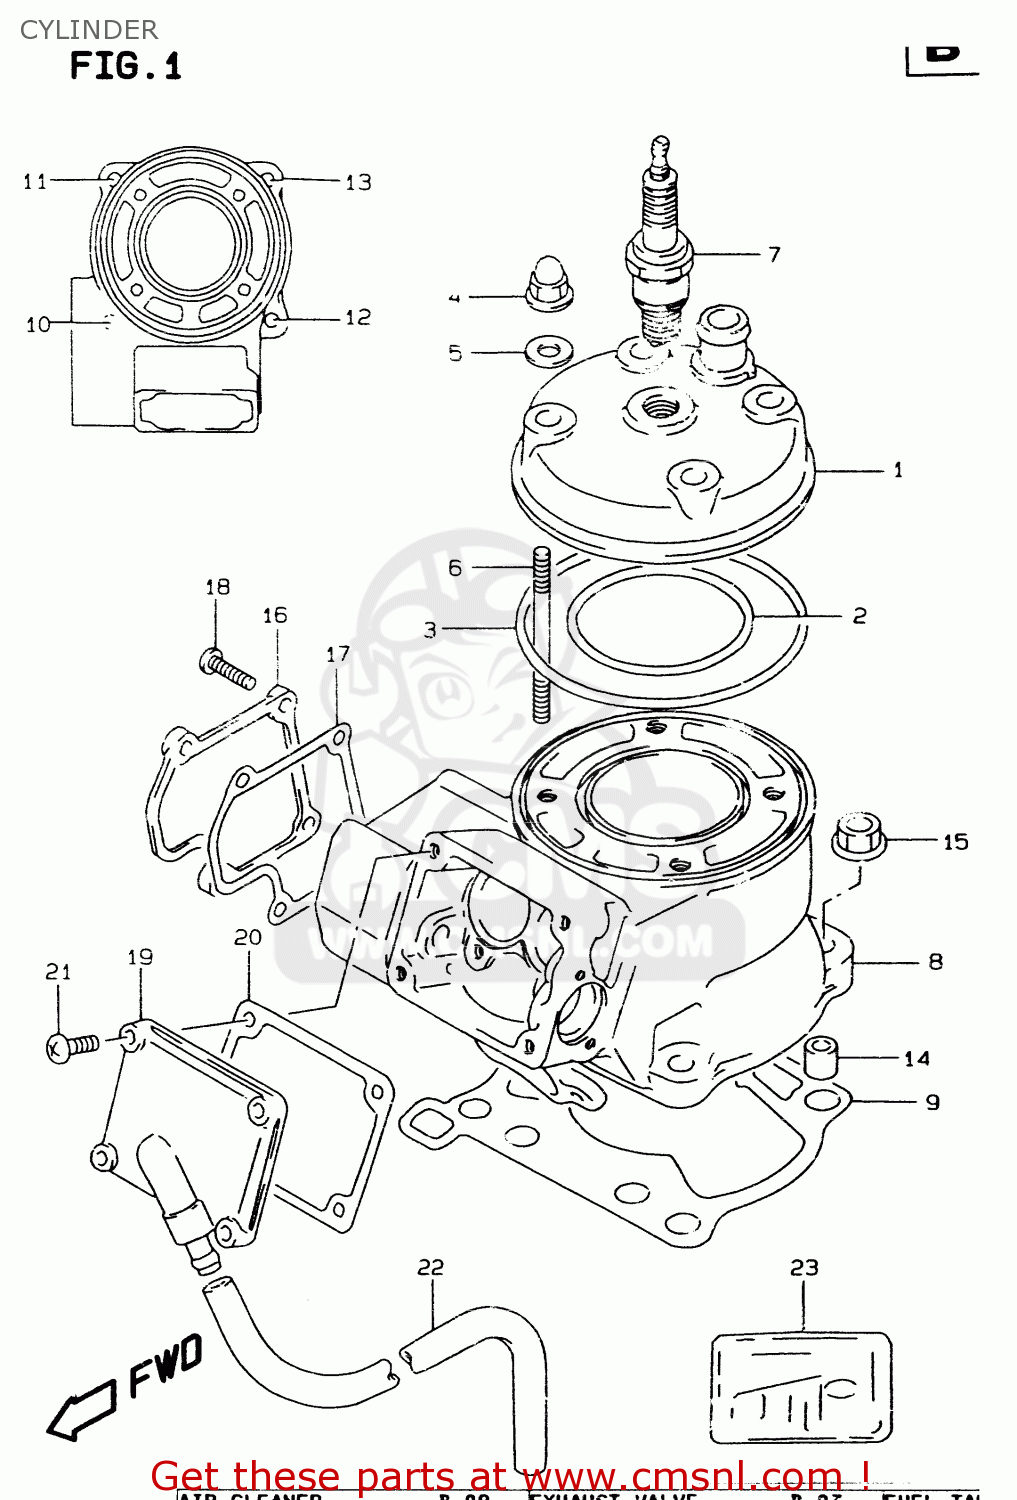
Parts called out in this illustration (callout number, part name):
1	HEAD,CYLINDER
2	O RING,CYLINDER HEAD NO.1
3	O RING,CYLINDER HEAD NO.2
4	NUT
5	GASKET(8.5X17X2.3) (NAS)
6	BOLT,STUD
7	SPARK PLUG B10ES
8	CYLINDER
9	GASKET,CYLINDER (NAS)
10	BOLT,STUD
11	STUD 8X25
12	BOLT,STUD
13	BOLT,STUD
14	PIN(8.4X11X14)
15	NUT
16	COVER,CYLINDER NO.1
17	GASKET,CYLINDER COVER NO.1 (NAS)
18	SCREW
19	COVER,CYLINDER
20	GASKET,CYL COVER NO.2 (NAS)
21	SCREW
22	HOSE(7X12X600)
23	GASKET SET (NAS)
